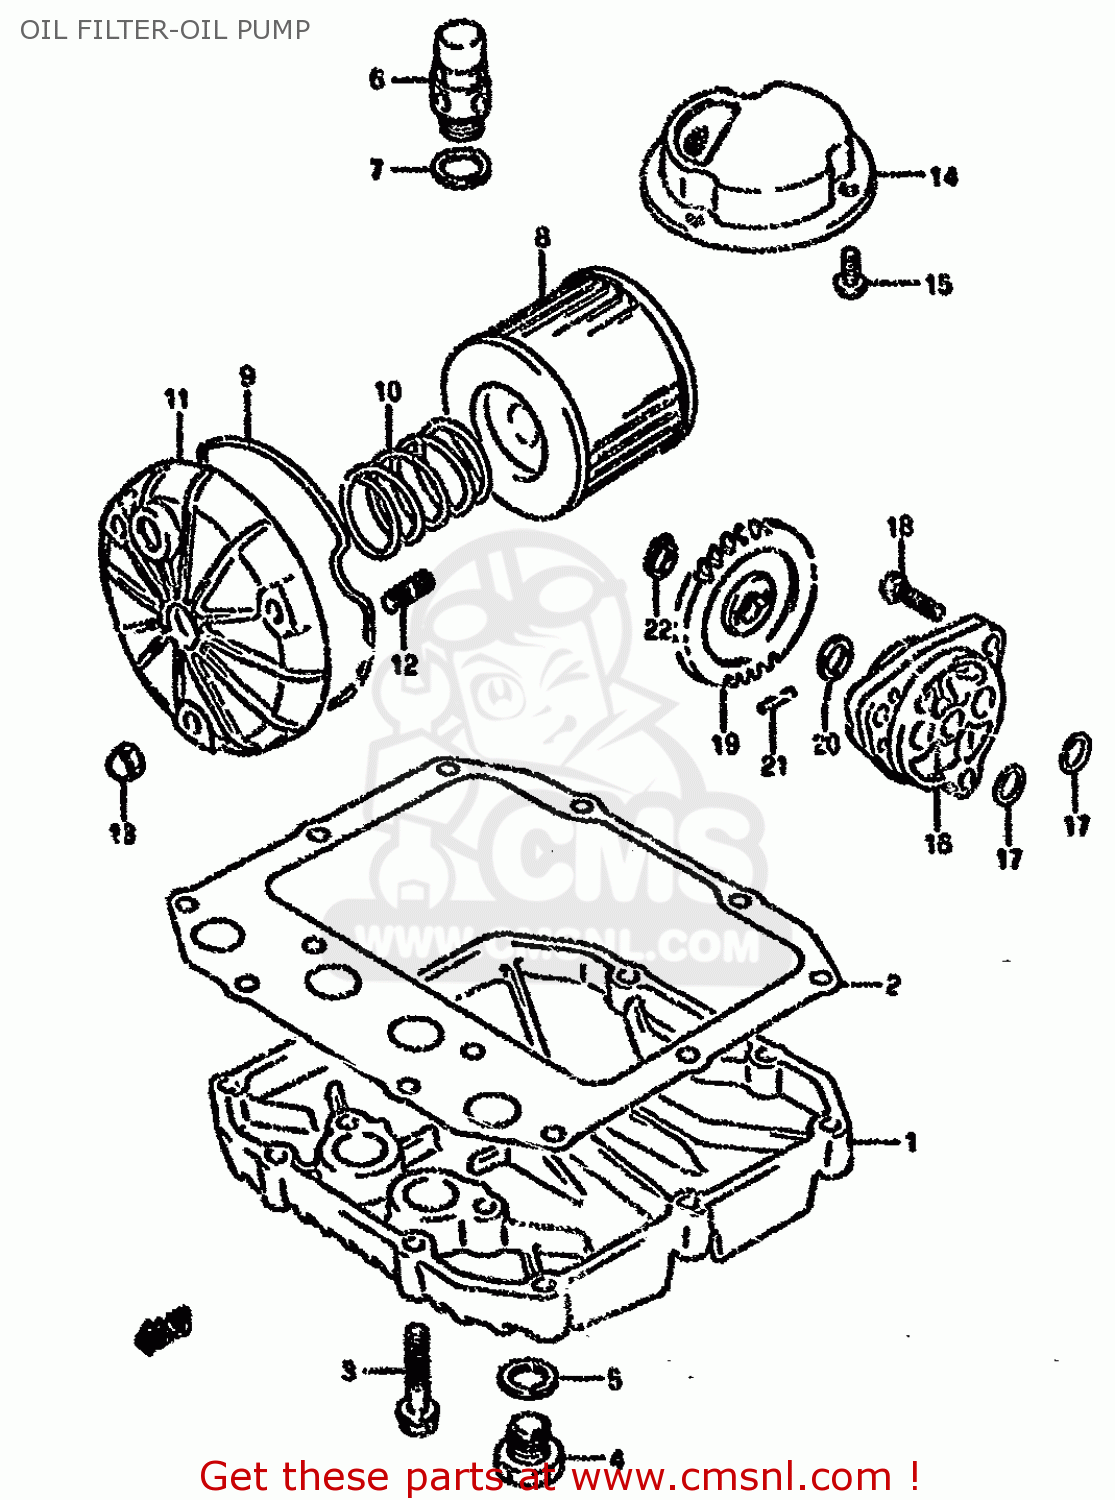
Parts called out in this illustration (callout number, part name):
1	PAN,OIL
2	GASKET,OIL PAN(ASB) (NAS)
3	BOLT
4	PLUG
5	GASKET(13.8X18.8X4.8) (NAS)
6	VALVE ASSEMBLY,OIL RELIEF
7	WASHER
8	FILTER ASSY,ENGINE OIL
9	O RING,OIL FILTER CHAMBER CAP
10	SPRING
11	CAP,OIL FILTER
12	STUD 6X20
13	NUT
14	STRAINER,ENGINE OIL
15	SCREW
16	PUMP ASSY,ENGINE OIL
17	O RING(D:1.9,ID:13)
18	SCREW
19	GEAR,OIL PUMP DRIVEN
20	SHIM
21	PIN(4X15.8)
22	CIRCLIP,10MM
